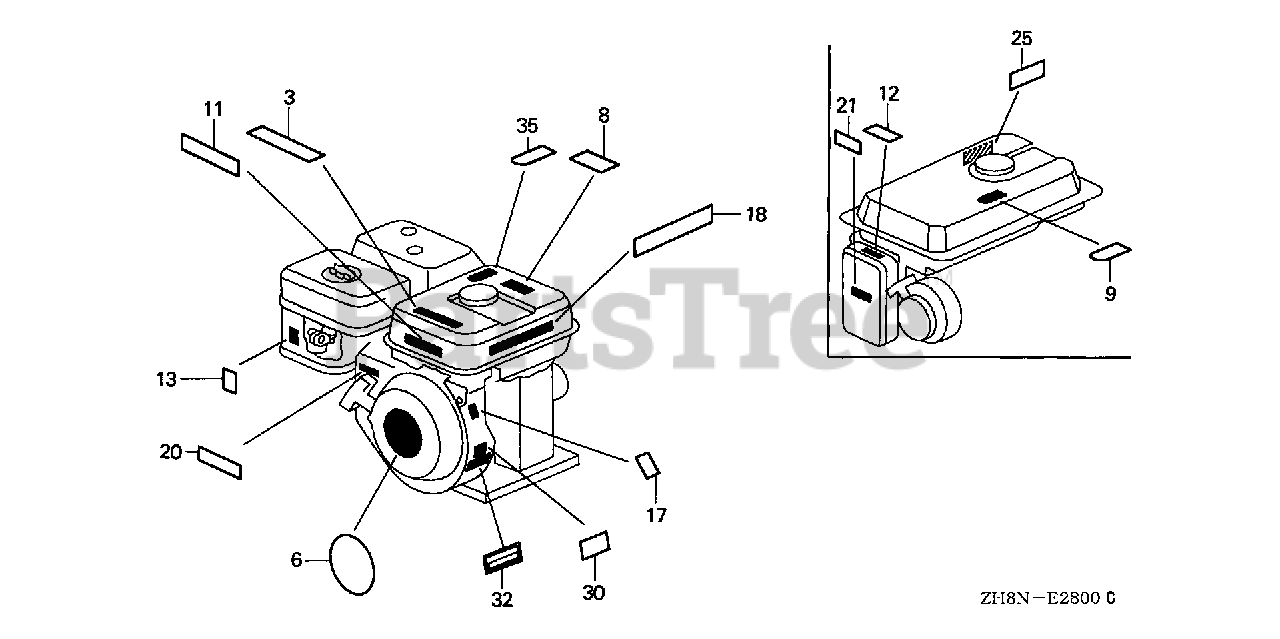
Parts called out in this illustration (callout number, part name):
6	EMBLEM (INTERNAL)
6	EMBLEM (5.5)
11	LABEL, CAUTION
13	MARK, CHOKE
32	MARK, OIL ALERT (E)
